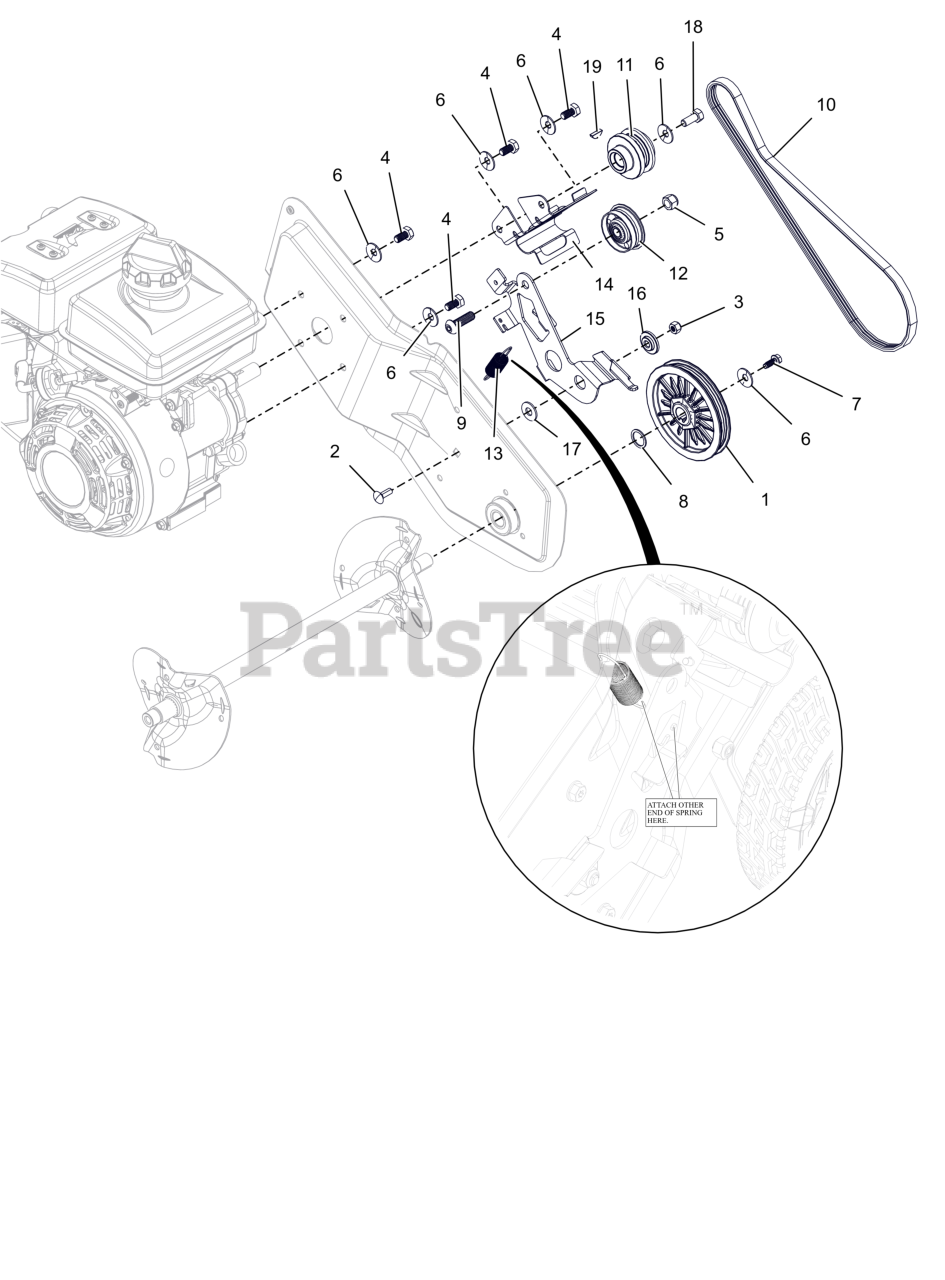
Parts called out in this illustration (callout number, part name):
1	PULLEY, ASM ROTOR
2	BLT, RDHDSQSHK .25-20X0.750 (BLACK)
3	NUT, NYLON .250 - 20 (BLACK)
4	SCR, CAP - M8X1.25 H6 THREAD
5	NUT,NYL .38-16 G5 ZCC
6	WSHR, BEVEL SPRING LOCK
7	1/4-20 X 5/8 TAPTITE
8	WSHR, THRUST
9	3/8-16X1.25 BHCS
10	V-BELT, RIBBED
11	PULLEY, ENGINE
12	PULLEY, IDLER
13	SPRG, BRAKE
14	GUIDE, BELT
15	ARM, IDLER
16	PULLEY, IDLER BUSHING
17	WSHR, FLAT .375X.875X.065 (BLACK)
18	BLT, HEX .31-24X.750 G5 ZCC
19	KEY, WDRF .157 X .630
